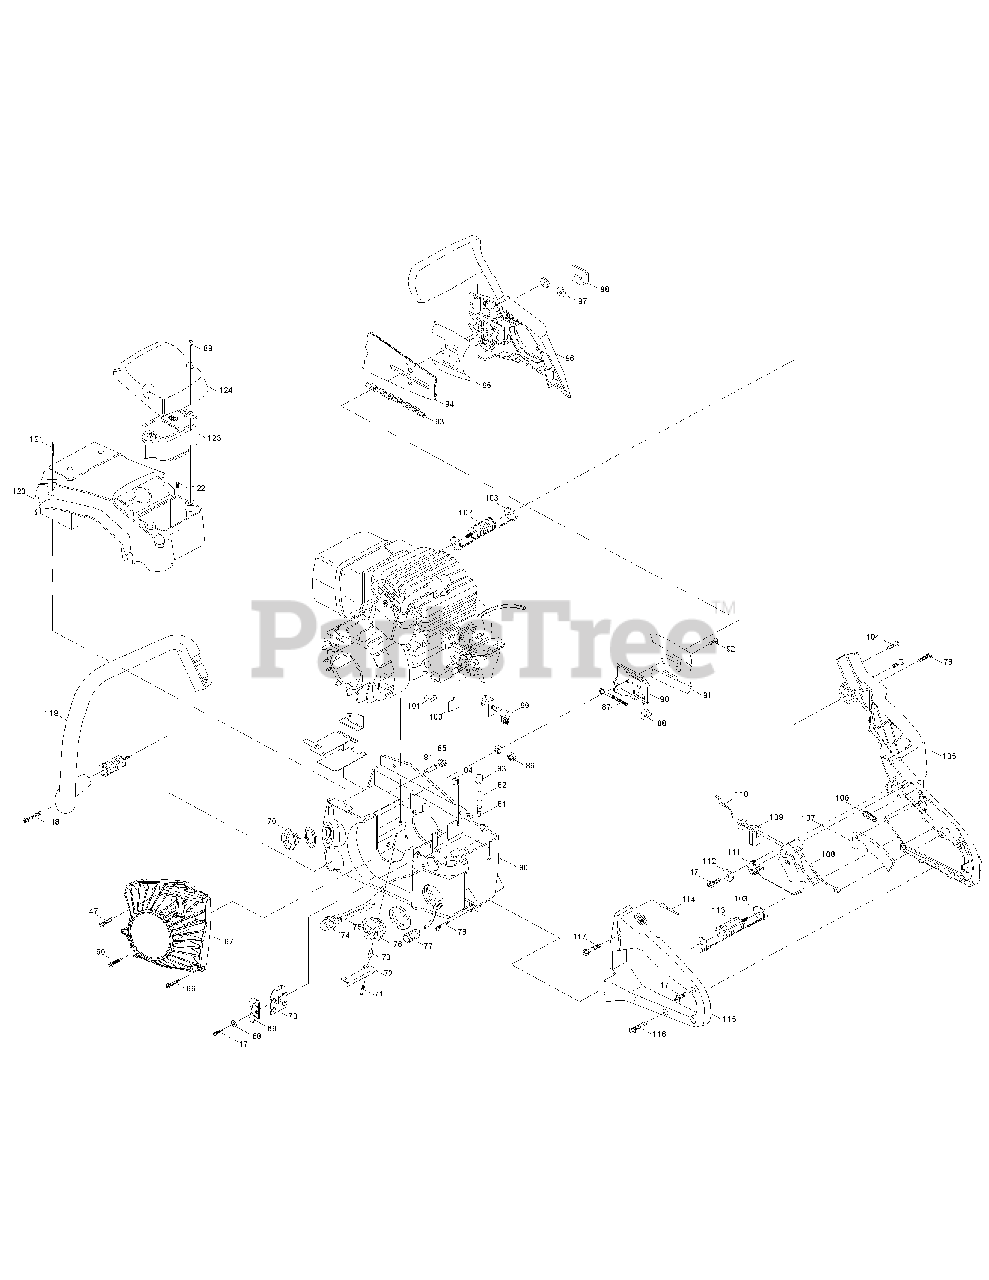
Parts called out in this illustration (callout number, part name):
8	CRANKCASE LOWER
10	C'SHAFT/C'ROD ASS'Y
13	GEAR, WORM
16	PUMP ASS'Y
20	DRUM SPRKT ASS'Y
21	CLUTCH ASS'Y
23	CRANKCASE UPPER
24	FITTING, PULSE LINE
26	CLAMP, WIRE HOSE
27	CONDUIT, FLEX
32	RING, PISTON
35	IGNITION ASS'Y
38	SCREW
39	FLANGE
42	SPARK PLUG
46	MUFFLER BODY ASS'Y
51	COVER, MUFFLER
52	LOCKPLATE
54	BOOT, CARBURETOR
59	CARBURETOR
67	STARTER ASS'Y
74	PRIMER, REMOTE
77	FILTER, FUEL
80	FUEL/OIL TANK ASS'Y
81	VALVE DUCKBILL
91	PLATE, FLANGE
93	20" CHAIN
96	CHAIN BRAKE ASS'Y
99	CHOKE ASS'Y
100	ROD, CHOKE
102	ISOLATOR ASS'Y
103	CABLE ASS'Y
107	RELEASE, TRIGGER
113	ISOLATOR ASS'Y
115	COVER ASS'Y, HANDLE
119	HANDLE ASS'Y
120	COVER ASS'Y
123	AIR CLEANER ASS'Y
126	CARRY CASE
